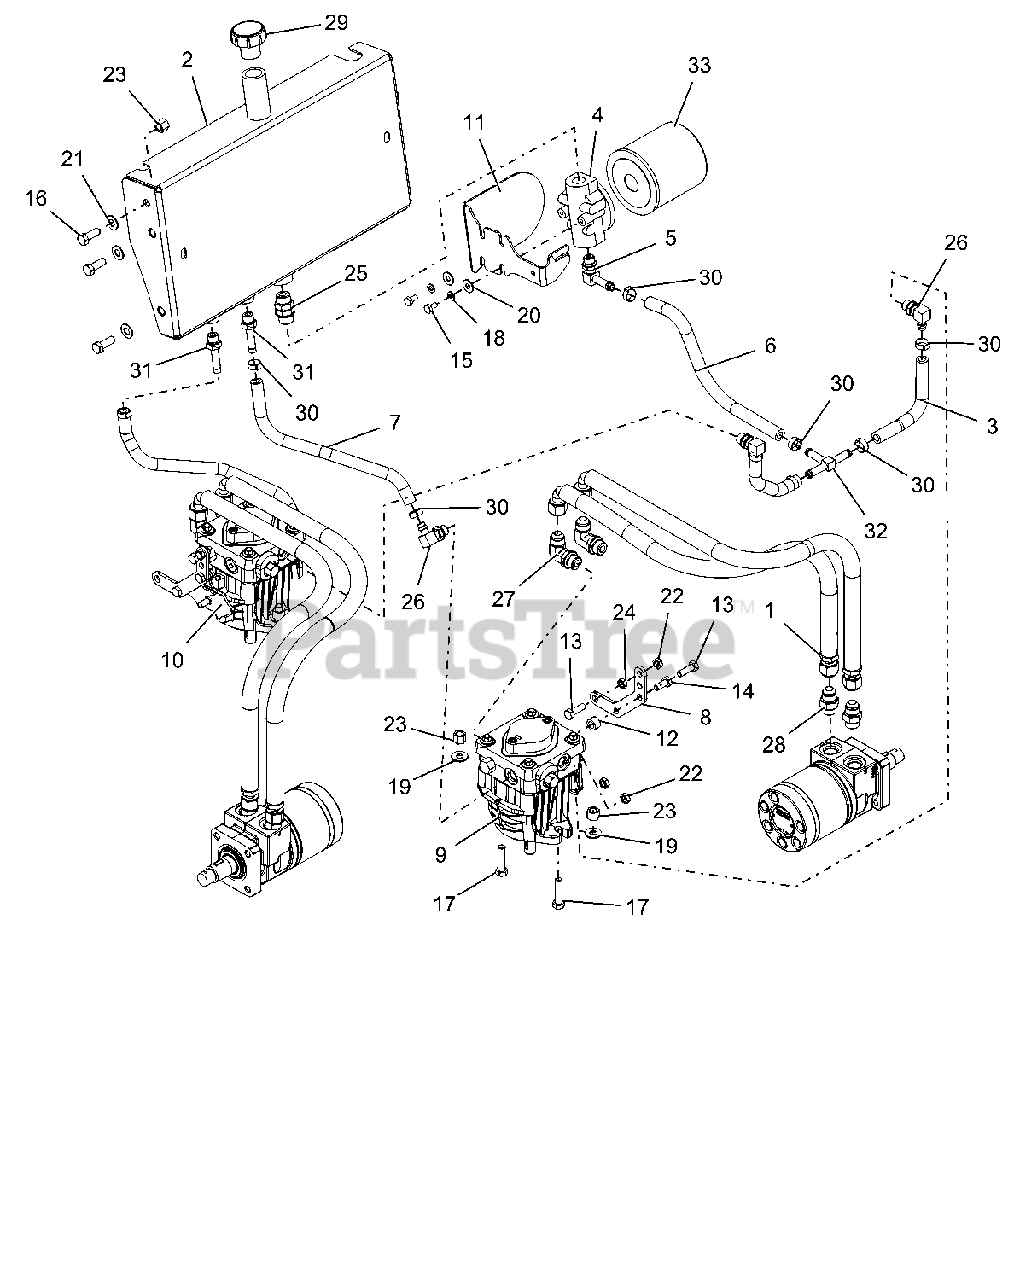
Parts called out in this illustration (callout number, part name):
1	HOSE, HYD 1/2 X 26 1/2 EZFLEX
2	WLDMT, TANK HYDRO STR PORT-RED
3	HOSE, HYD 3/8 X 6.00
4	HEAD, OIL FILTER
5	FTG, 90 BRB-OR 4601-06-08
6	HOSE, HYD .375X10.5
7	HOSE, HYD .375X14.00
8	BRACKET-PUMP CONTROL-BLACK
9	PUMP, LH HYD PE (10CC)
10	PUMP, RH HYD PE (10CC)
11	GUARD, HYDRO FILTER-RED
12	BSHG, SLV REV
13	BLT-HEX .31-18X1.00 GR5 YWZC
14	BLT-HEX .31-18X.75 GR5 YWZC
15	BLT-HEX .25-20X.50 GR5 YWZC
16	BLT-HEX .38-16X1.00 GR5 YWZC
17	BLT-HEX .38-16X1.50 GR5 YWZC
18	WSHR-LK .25X.062 REG YWZC
19	WSHR-FL-STL.38X.875X.083 YWZC
20	WSHR-FL-STL.312X.734X.065 YWZ
21	WSHR-FL-STL.406X.812X.065 YWZ
22	NUT-LK-CTR-JAM .31-18 YWZC
23	NUT-LK-NYL .38-16 YWZC
24	NUT, JAM .312-18 YWZC
25	FTG, STR UNION M80-M80
26	FTG, 90 9/16MOR X 3/8HOSE SHRT
27	FTG, ADP JIC-ORB 6801-08-08
28	FITTING, STRAIGHT
29	CAP, OIL FILL BREATHER
30	CLAMP, HOSE - 1/2" PINCH
31	ADAPTER, STRAIGHT FITTING
32	FTG, TUN 3/8 HOSE
33	FILTER, OIL
